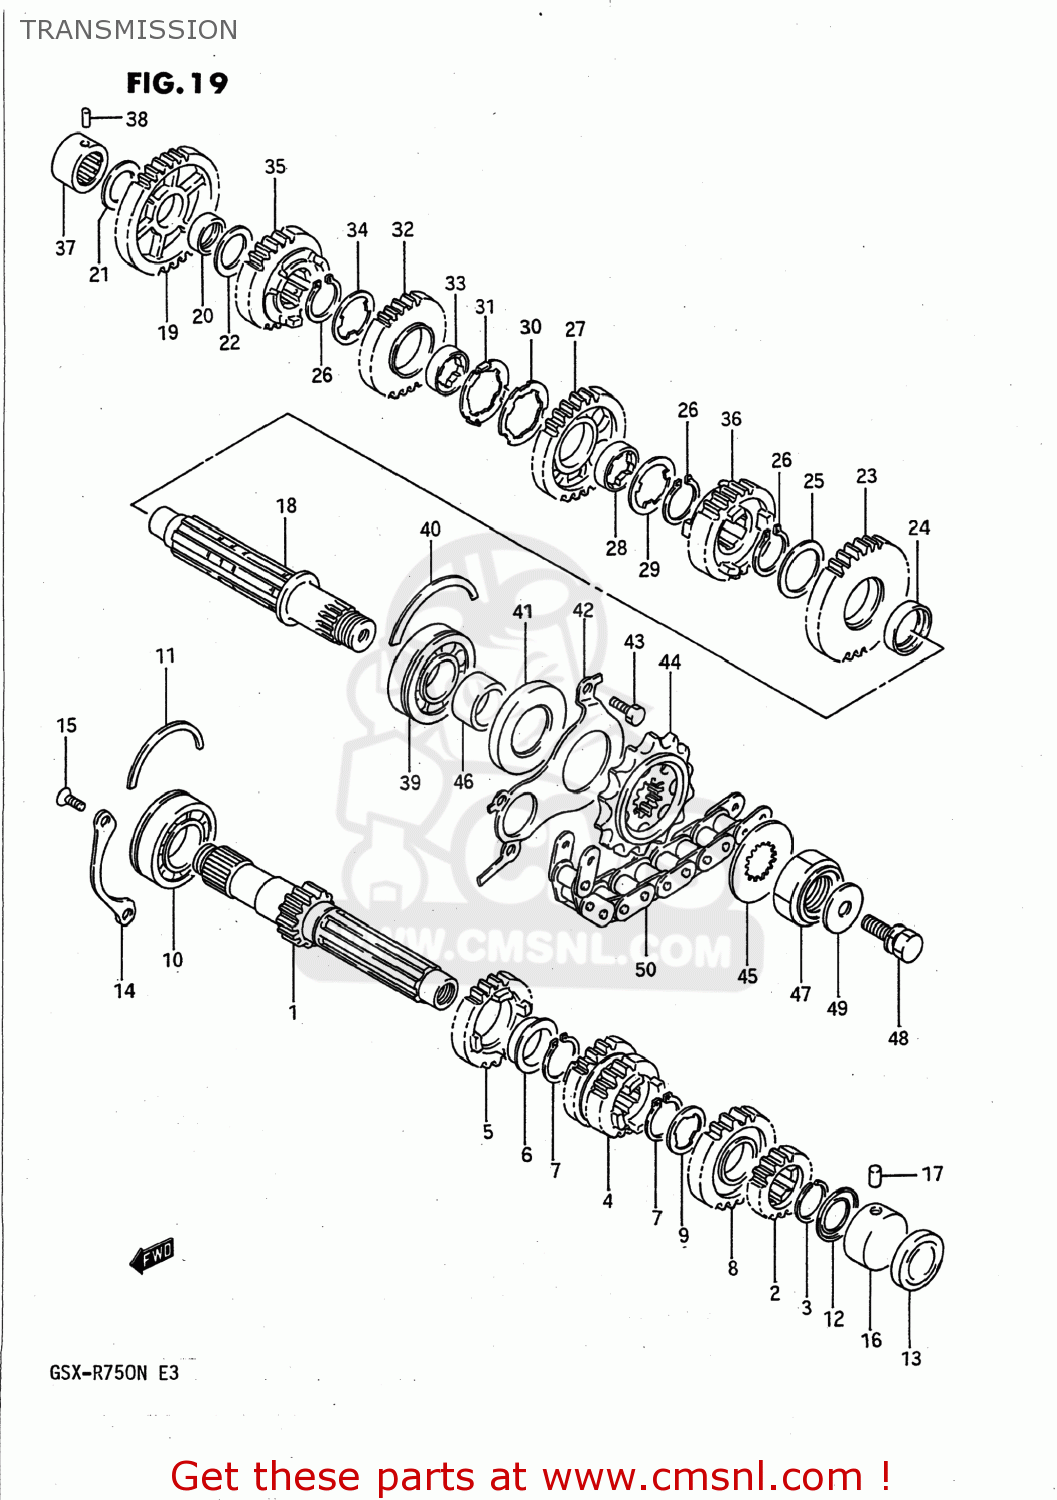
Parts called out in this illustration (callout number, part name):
1	SHAFT,COUNTER(NT:13)
2	GEAR,2ND DRIVE(NT:16)
3	CIRCLIP
4	GEAR,3RD & 4TH DRIVE(NT:17/20)
5	GEAR,5TH DRIVE(NT:22)
6	BUSHING
7	RING,SNAP
8	GEAR,SIXTH DRIVE (NT:21)
9	WASHER,LOCK
10	BEARING(25X62X17)
11	C-RING
12	SEAL,OIL(20X31.2X2.7)
13	CAP,COUNTER SHAFT,L
14	RETAINER,CNTR SHAFT BEARING
15	SCREW
16	BEARING(20X34X17.5)
17	PIN
18	SHAFT,DRIVE
19	GEAR,1ST DRIVEN(NT:36)
20	BUSH(22X26X9)
21	WASHER
22	WASHER
23	GEAR,2ND DRIVEN(NT:33)
24	BUSH(28X32X8)
25	WASHER, THRUST
26	CIRCLIP
27	GEAR,3RD DRIVEN
28	BUSH
29	WASHER,LOCK
30	WASHER,LOCK
31	WASHER
32	GEAR,4TH DRIVEN(NT:28)
33	BUSH
34	WASHER,LOCK
35	GEAR,5TH DRIVEN(NT:27)
36	GEAR,6TH DRIVEN
37	BEARING(20X34X20)
38	PIN
39	BEARING(25X62X17)
40	C-RING
41	SEAL,OIL(34X62X6)
42	RETAINER,DRIVE SHAFT OIL SEAL
43	BOLT
44	SPROCKET,ENGINE (NT:15)
45	WASHER,THRUST
46	SPACER,ENGINE SPROCKET
47	NUT
48	BOLT
49	WASHER
50	CHAIN ASSEMBLY,DRIVE 50GSV
